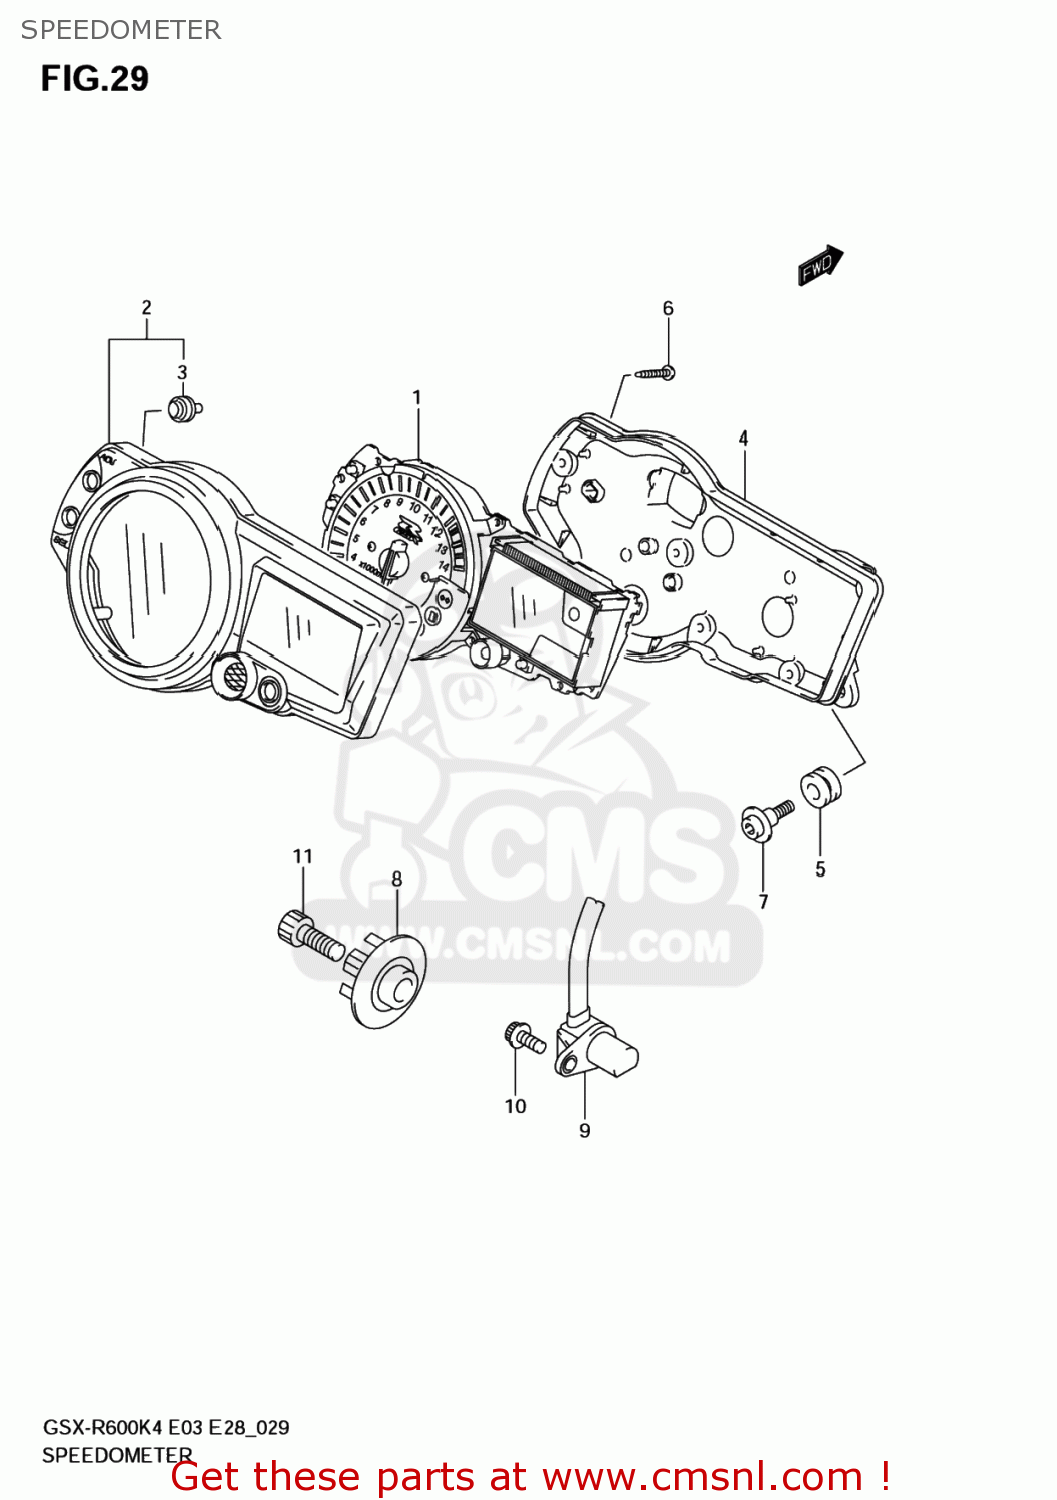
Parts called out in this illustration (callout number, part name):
1	SPEEDOMETER
2	CASE,SPEEDOMETER UPR
3	SWITCH,LEVER
4	CASE,SPEEDOMETER LWR
5	CUSHION,METER
6	SCREW(3X16)
7	SCREW,SPEEDOMETER
8	ROTOR,SPEED
9	SENSOR,SPEED
10	BOLT
11	BOLT
